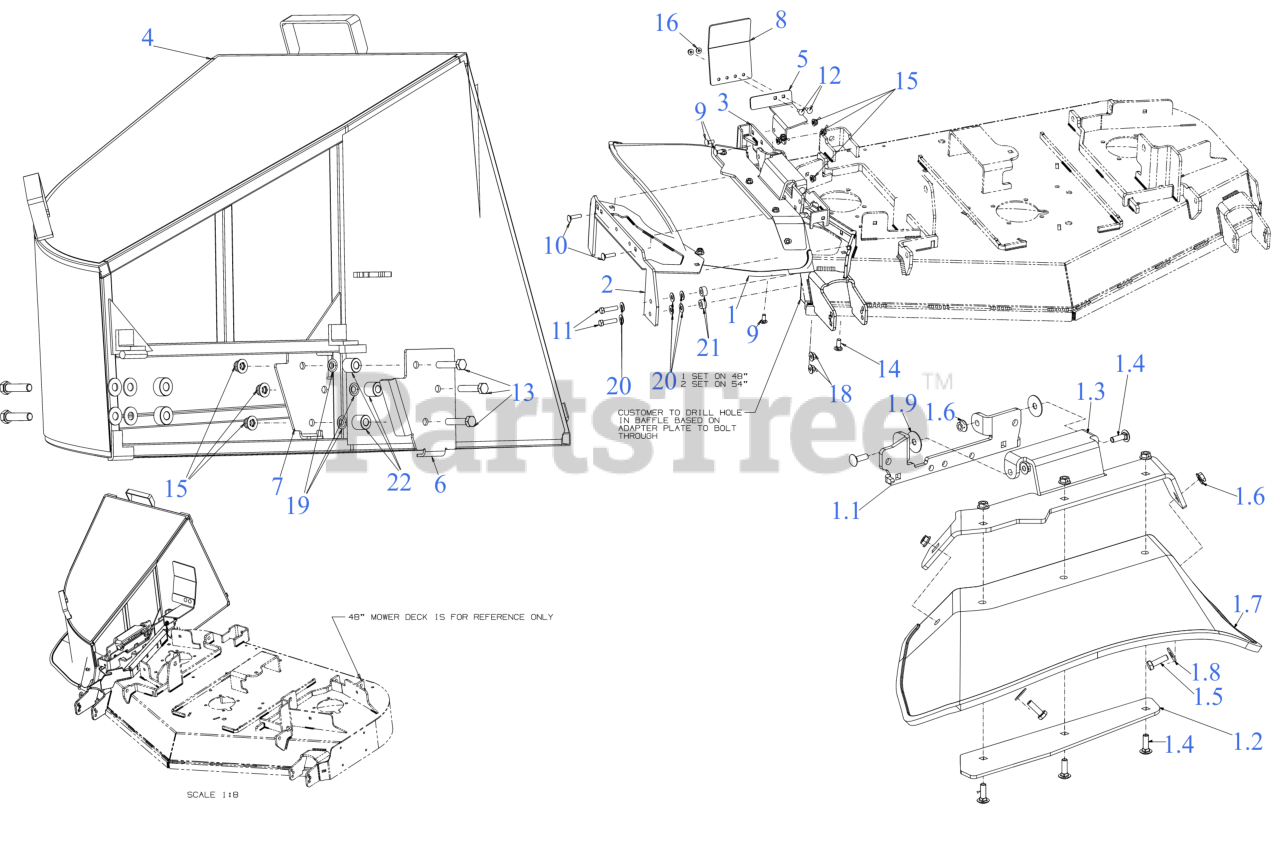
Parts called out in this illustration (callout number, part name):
1	DECK CHUTE ASSEMBLY
1.1	CHUTE BRACKET
1.2	CHUTE SUPPORT PLATE
1.3	CHUTE BRACKET
1.4	CARRIAGE BOLT 5/16-18 x 1.00
1.5	SCREW 5/16-18 x 1.0 GR5
1.6	HEX FLANGE NUT
1.7	FIBER FORMED CHUTE
1.8	FLAT WASHER
1.9	WASHER .355X1.25X.048THK
2	WELD ASSEMBLY
3	MOUNT BRACKET
4	GRASSCATCHER CAGE
5	DEFLECTOR CHUTE BRACKET
6	OUTER BAG BAFFLE
7	INNER BAG BAFFLE
8	DEFLECTOR BRACKET
9	CARRIAGE BOLT 5/16-18 x .75
10	CARRIAGE BOLT 5/16-18 x 1.25
11	SCREW 3/8-16 x 1.50
12	SCREW 1/4-20 x .75 GR5
13	SCREW 5/16-18 x 1.5 LG
14	CARRIAGE BOLT 3/8-16 x 1.00 GR5
15	FLANGE LOCK NUT 5/16-18
16	FLANGE LOCK NUT
18	FLANGE LOCK NUT
19	PUSH NUT
20	FLAT WASHER
21	SPACER .385X.875X.458 LG
22	SPACER .34 x .75 x .63 LG
